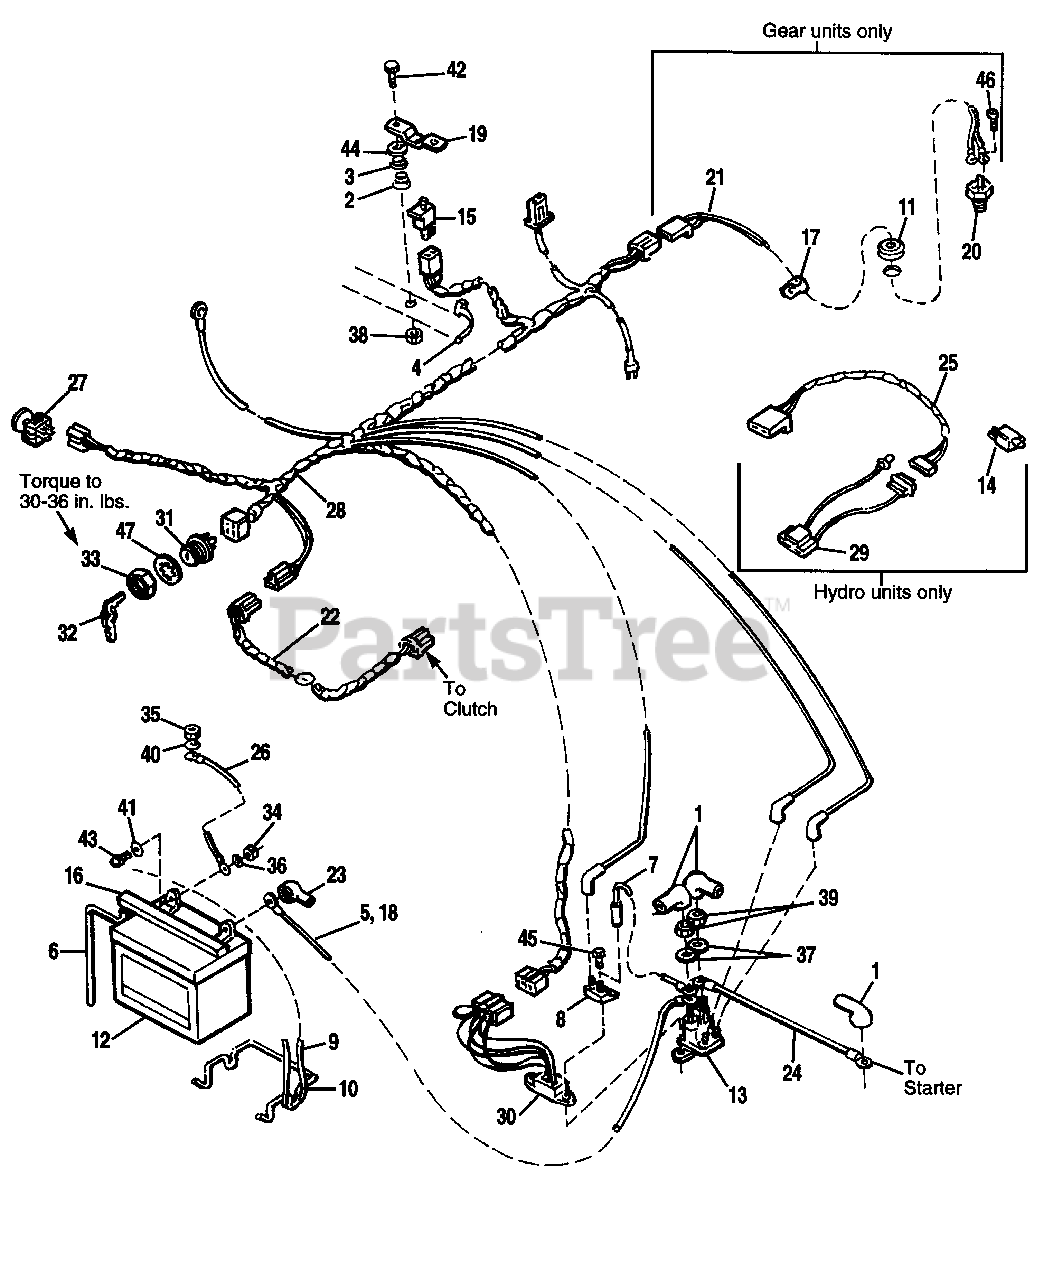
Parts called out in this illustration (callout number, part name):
1	COVER, Terminal
4	CLIP
5	CABLE, Battery to Solenoid
8	CIRCUIT BREAKER
9	STRAP, Battery
10	BRACE, Battery
13	SOLENOID
14	SWITCH, Neutral Start (Hydro model)
15	SWITCH, Seat
16	BATTERY CAP
17	CLAMP, Wire
18	CABLE, Battery to Solenoid
19	PLATE, Seat Actuator
20	NEUTRAL SWITCH (Gear model)
21	WIRE ASSY., Neutral Switch (Gear model)
22	WIRE ASSY., PTO Clutch
23	BOOT, Insulator
24	CABLE, Solenoid to Starter
25	WIRE ASSY., Neutral Switch (Hydro model)
26	CABLE, Battery, Ground
27	SWITCH, PTO, Electric Clutch
28	WIRING HARNESS
29	ADAPTER PLUG, Engine
30	MODULE, Interlock
31	SWITCH, Ignition
32	KEY, Ignition
33	ADAPTER, Nut
34	NUT, Hex, 1/4-20
35	NUT, Hex, 3/8-16
36	LOCKWASHER, 1/4
37	LOCKWASHER, 5/16
38	NUT, Hex, Nylon Lock, 5/16-18
39	NUT, Hex, 5/16-24
40	LOCKWASHER, External Tooth, 3/8
41	WASHER, Plain
42	CAPSCREW, Hex Hd., 5/16-18 x 1-3/4
43	CAPSCREW, Hex Hd., 1/4-20 x 3/4
44	WASHER, Flat, 13/32 x 7/8 x 5/64
45	SCREW, Hex, Flange, Taptite, 1/4-20 x 1/2
46	SCREW, Taptite, #10-20 x 5/8 (Gear model)
47	WASHER, Internal Tooth, 5/8
